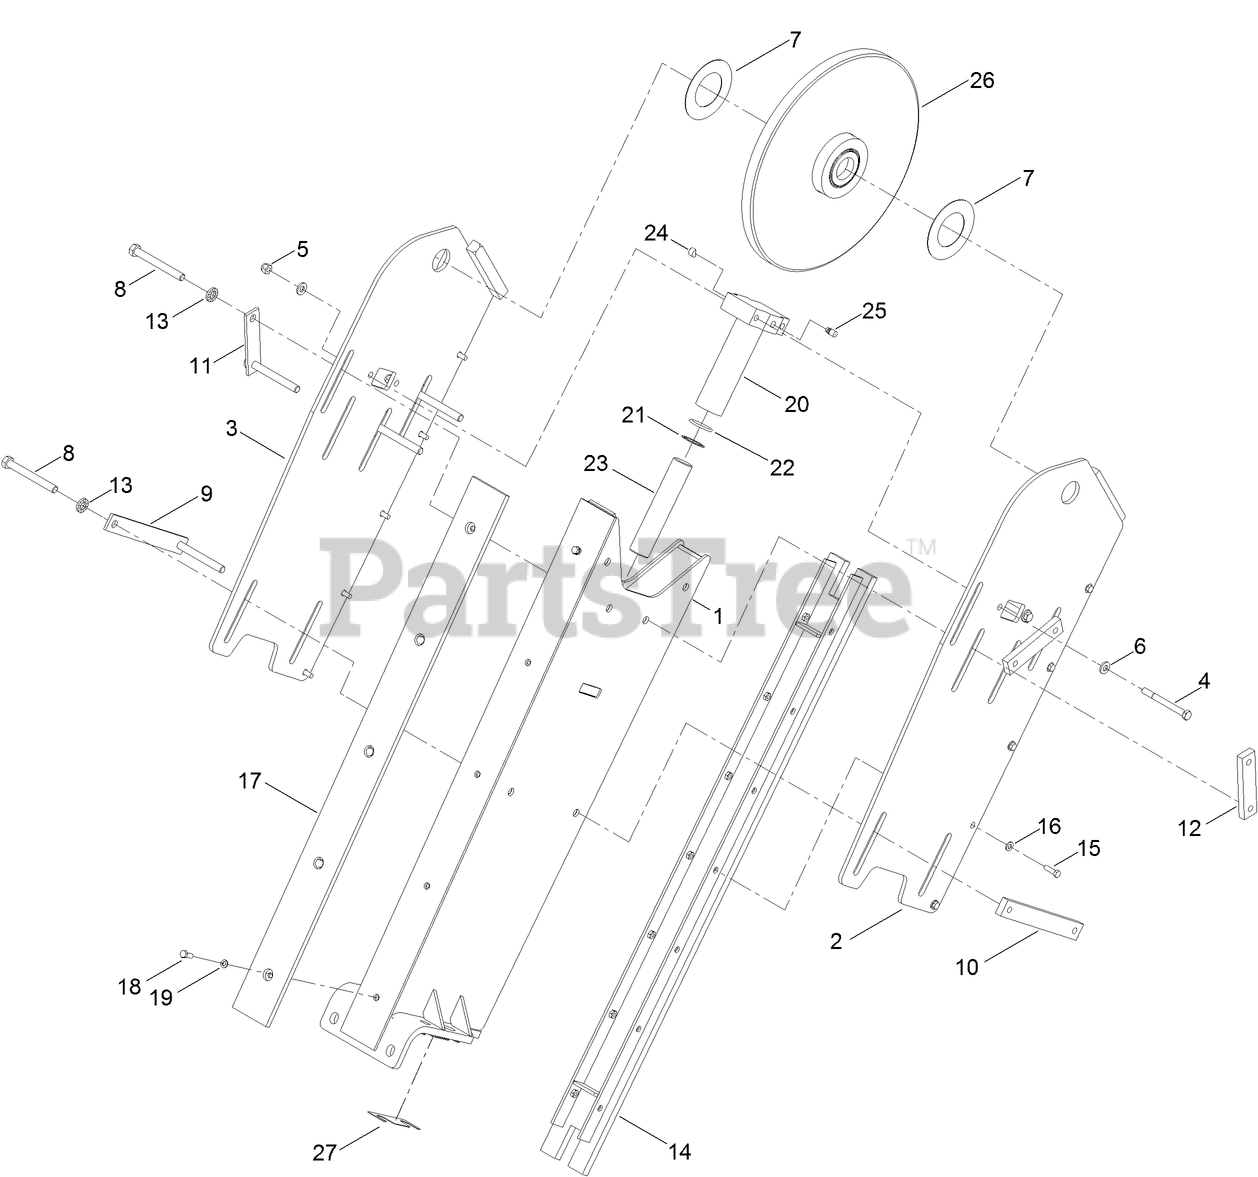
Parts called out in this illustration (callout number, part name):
1	BOOM-ROCK, 5 FOOT
2	PLATE-BOOM END LH
3	PLATE-BOOM END RH
5	NUT-HEX
7	WASHER-BOOM, END (ROLLER)
8	SCREW-HH
9	BAR-WASHER, LONG
10	BAR-TAPPED, LONG
11	BAR-WASHER, SHORT
12	BAR-TAPPED, SHORT
13	WASHER-LOCK
14	CHANNEL-WEAR PAD, 5 FOOT
15	SCREW-HH
16	WASHER-FLAT
17	BAR-WEAR PAD, 5 FOOT
18	SCREW-HH
19	WASHER-LOCK
20	CYLINDER ASM (BOOM END)
21	WASHER-BACKUP
23	ROD-BOOM, END (CYLINDER)
24	PLUG-BLEED
25	FITTING-LUBE, STRAIGHT
26	BOOM END ASM
